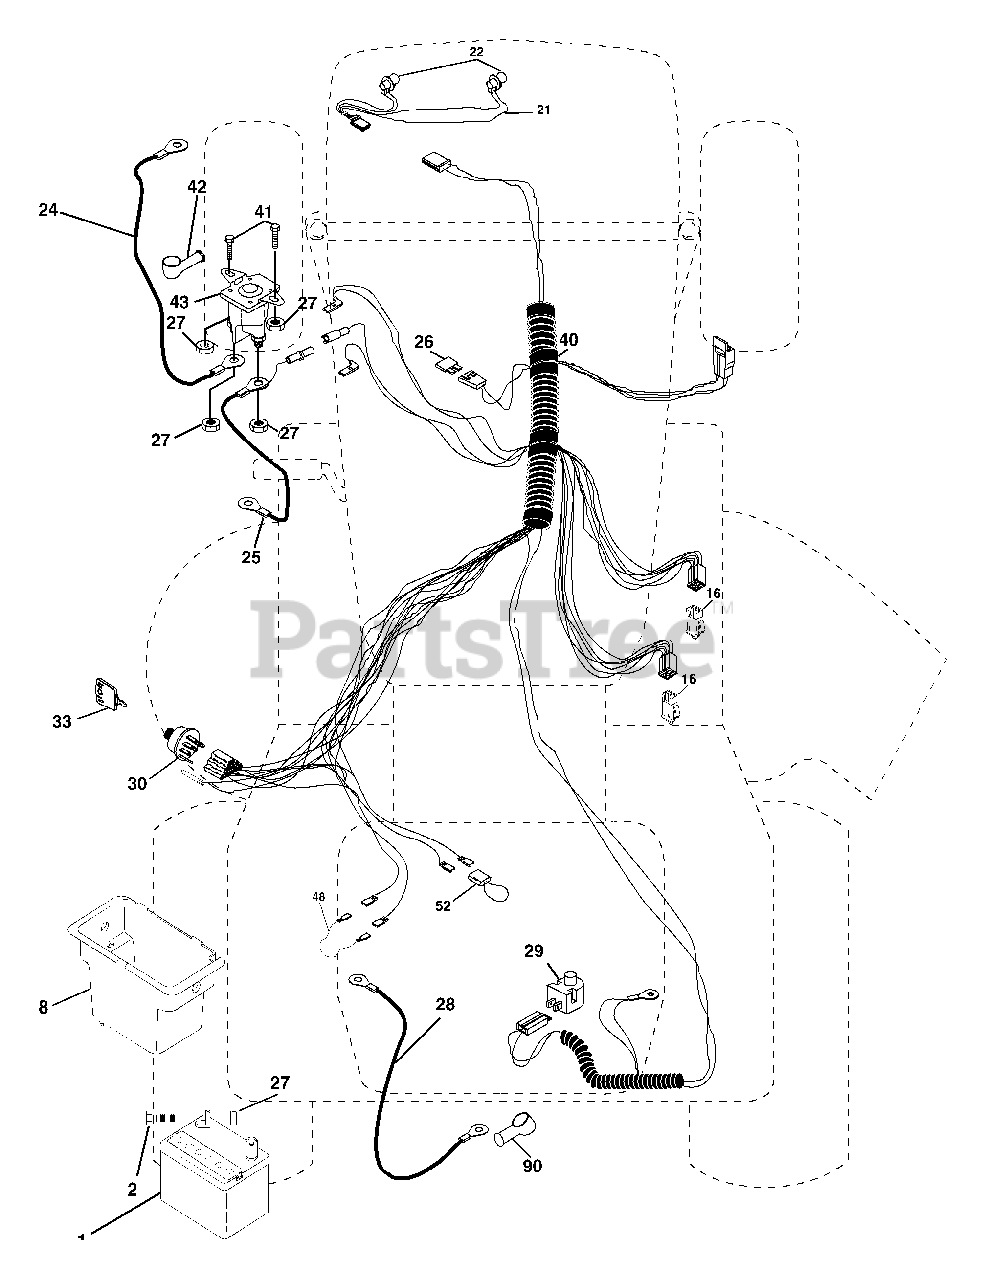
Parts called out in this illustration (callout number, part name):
1	Battery
2	Bolt, Hex Head 1/4-20 unc x 3/4
8	Box Battery Fender
16	Switch, Interlock
21	Harness, Light Socket
22	Bulb, Light
24	Cable, Battery, 6 Gauge, Red, 11"
25	Cable, Battery, 6 Gauge, Red, W/16 Wire
26	Fuse
27	Nut Keps Hex 1/4-20 UNC
28	Cable, Ground, 6 Gauge, Black, 12"
29	Switch, Plunger
30	Switch, Ignition
33	Key, Ignition
40	Harness, Ignition
41	Bolt, Hex Head, Fin. 1/4-20 x 1/2
42	Cover, Terminal, Red
43	Solenoid
48	Adaptor Ammeter Rectangular
52	Protection Wire Loop
90	Cover Terminal Battery
